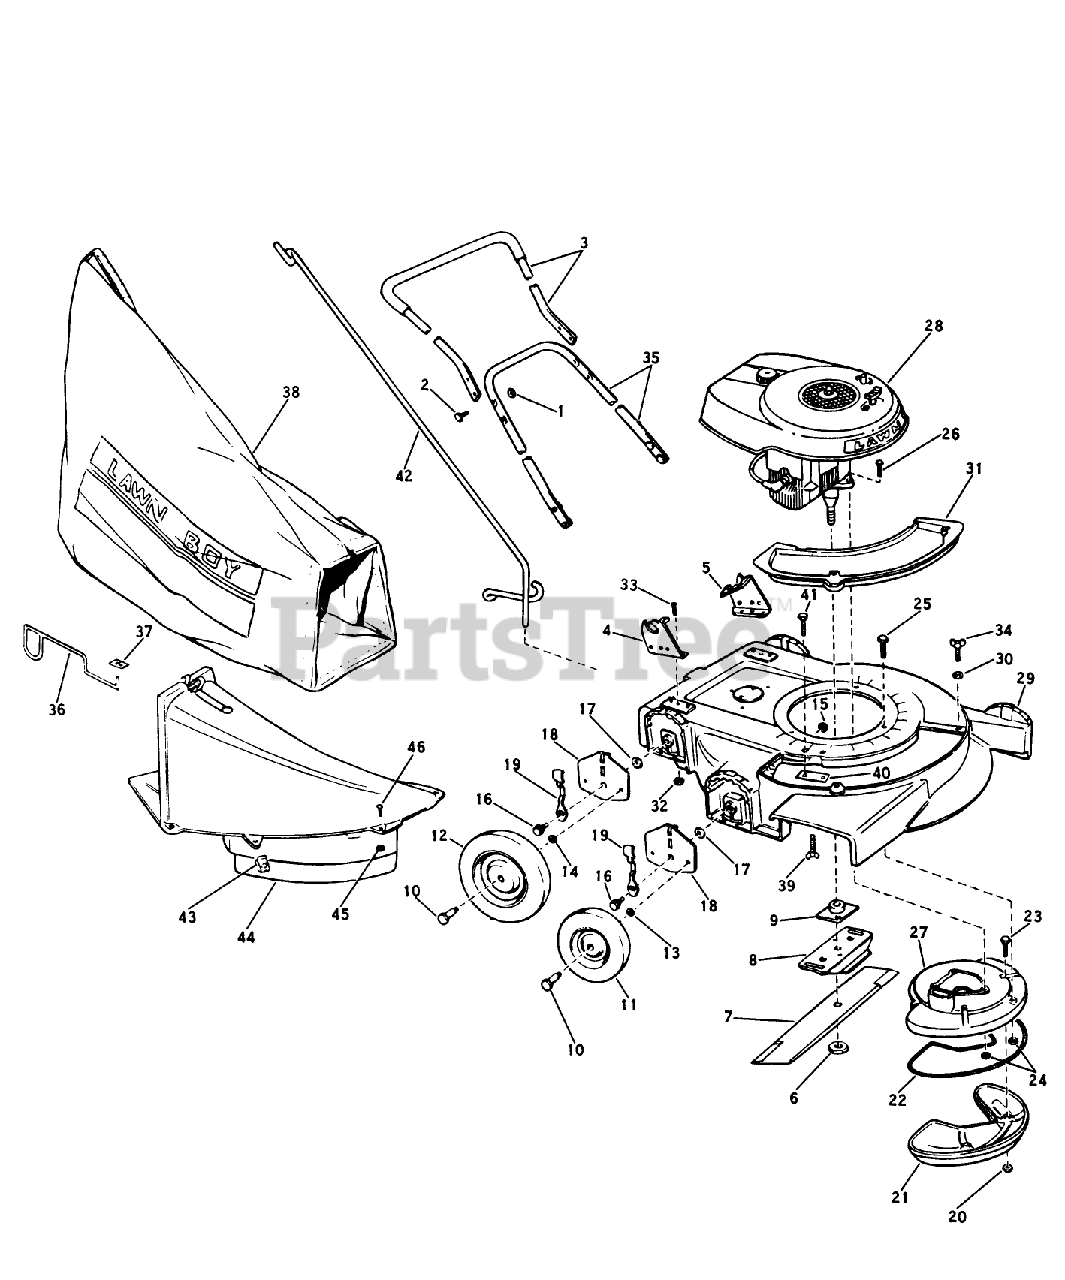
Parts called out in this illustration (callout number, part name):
3	Handle Grip Assy. Top
6	NUT-BLADE
9	PLATE AND COLLAR ASM
10	BOLT WHEEL
13	WASHER WROUGHT
14	WASHER WROUGHT
20	LOCKNUT E
29	Housing Cover Assy. 19"
33	SCREW S
38	89802 LB WHOLE GOODS
43	SPEED NUT ARDEN
44	Chute Skirt Assembly (Includes Hardware)
